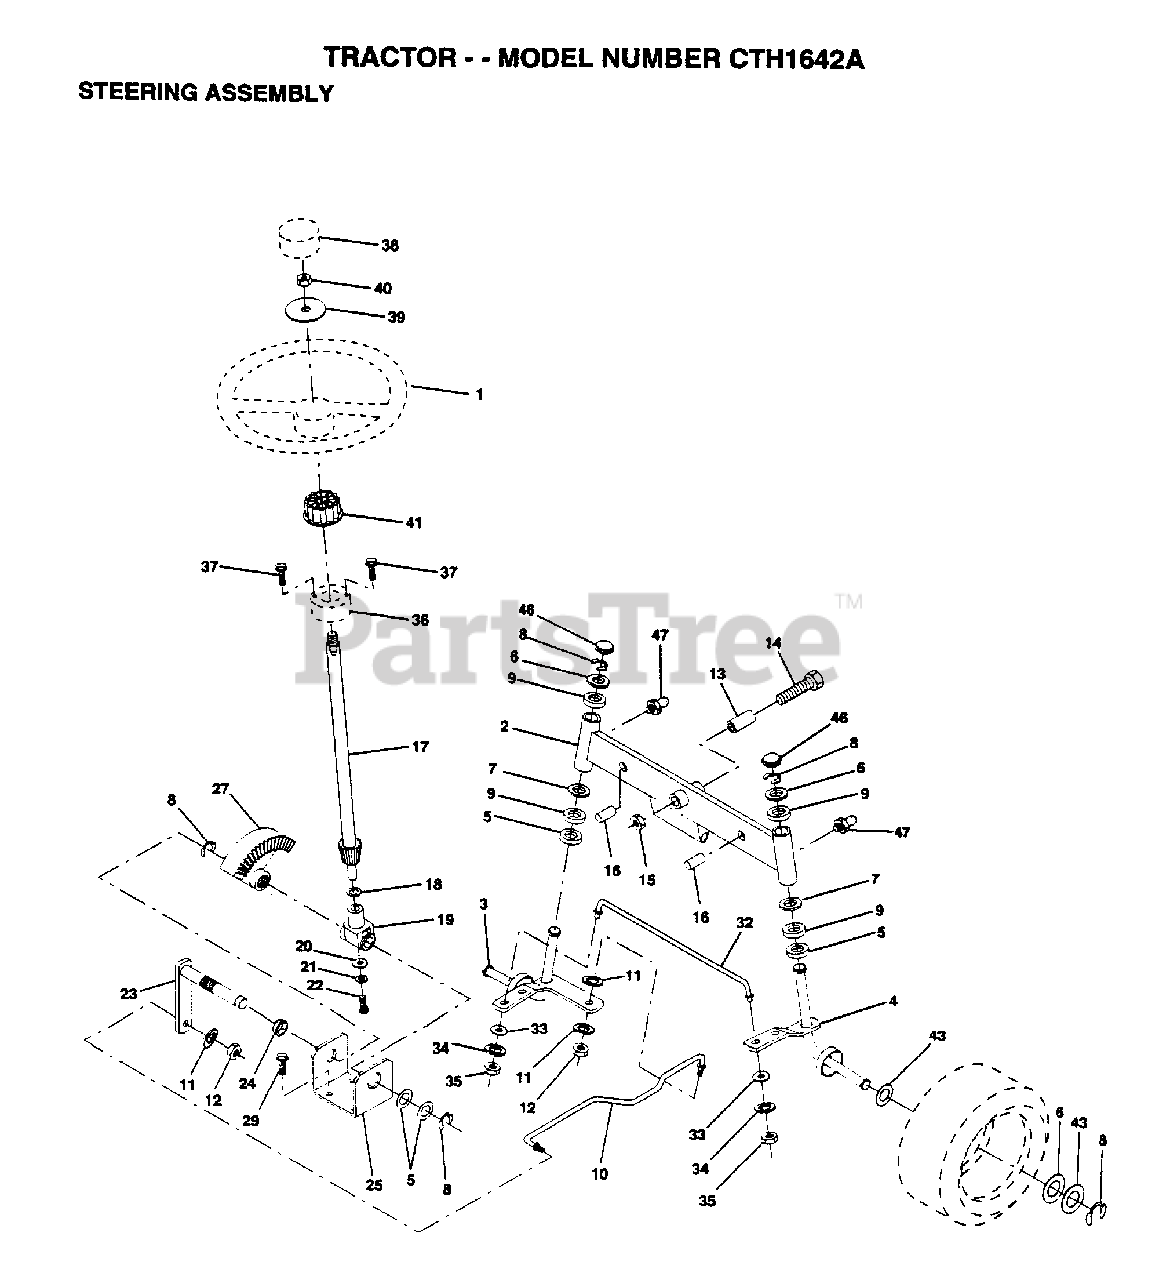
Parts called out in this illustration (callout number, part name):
1	WHEEL STR AYP BLK
2	AXLE ASM FRONT
3	SPINDLE LH
4	SPINDLE RH
5	WASHER .T
6	WASHER
7	WASHER
8	RING
9	COL. SRTG. BEAR.
11	LOCKWASHER
13	BEARING
14	BOLT HEX 5/8-11
15	"NUT-LOC,FLANGE LT"
16	AXLE PIN
17	STEERING SHAFT
18	THRUST WASHER
19	SUPPORT.SHAFT
21	LOCKWASHER
22	"SCREW,SPECIAL"
24	NYLINER T
25	"BRKT,STEERING"
27	GEAR SECTOR
29	SCREW
32	ROD.TIE.19.75
33	WASHER M
34	LOCKWASHER
35	NUT.LOCK.5/16-24
36	BUSHING.STRG.3/4
37	SCREW.10-24X1/2
38	CAP STEER AYP
39	WASHER
41	ADAPTER LT
43	WASHER
46	CAP
47	ZERK M
